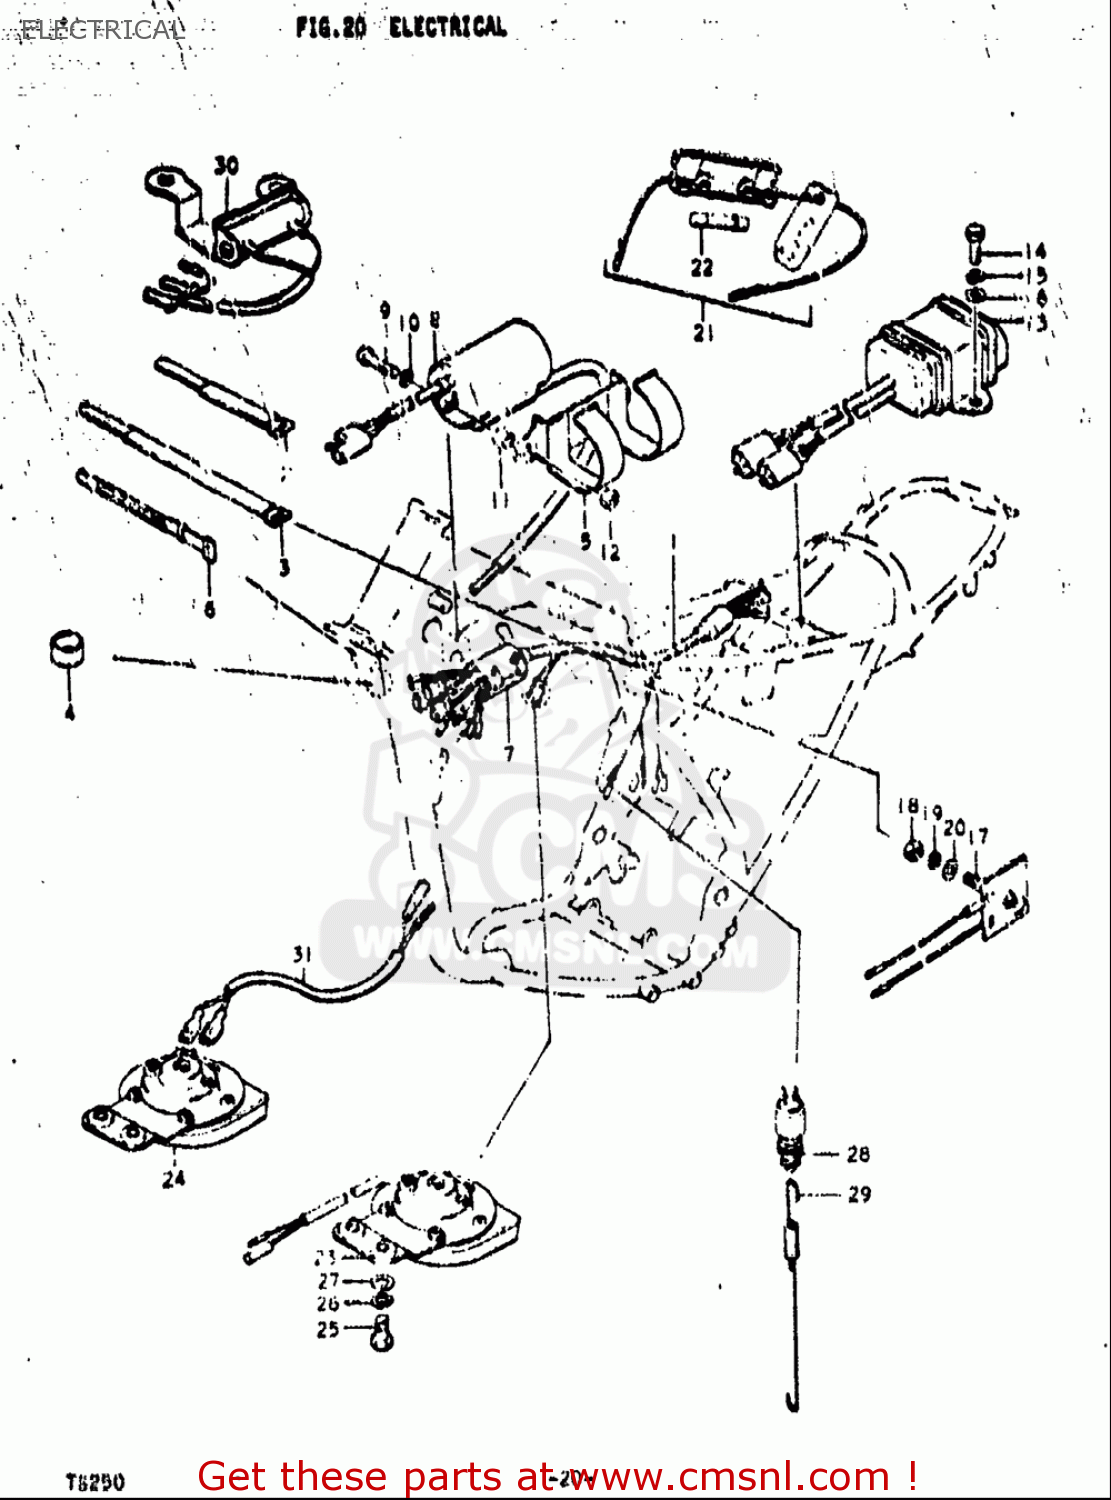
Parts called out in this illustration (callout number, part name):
2	CLAMP
3	CLAMP(L:250)
6	CLAMP(L:120)
7	BOOT,WIRING HARNESS
8	COIL ASSY,IGNITION
9	SCREW
10	WASHER,LOCK
12	NUT
14	BOLT(6X20)
15	WASHER,LOCK
18	NUT
19	WASHER,LOCK
20	WASHER
21	CASE ASSY,FUSE
22	FUSE(15A)
23	HORN ASSEMBLY
24	HORN ASSEMBLY
25	BOLT
26	WASHER,LOCK
27	WASHER
28	SWITCH ASSY,BRAKE LAMP
29	SPRING
